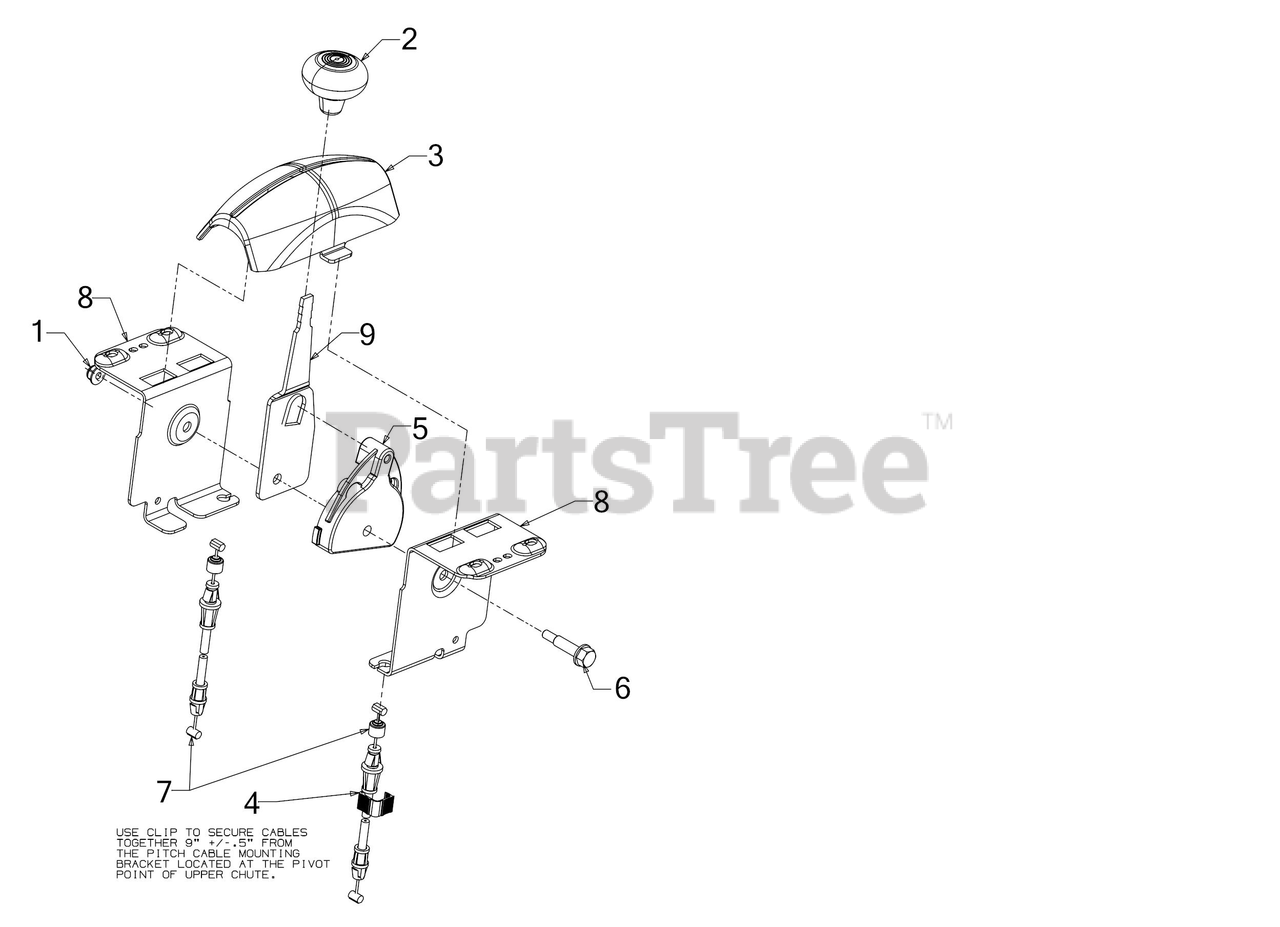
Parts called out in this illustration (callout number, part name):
1	FLANGE LOCK NUT
2	SHIFT KNOB
3	2 WAY CONTROL COVER
4	CABLE CLIP
5	CABLE GUIDE
6	SHOULDER SCREW
7	2-WAY CHUTE CONTROL CABLE
8	2 WAY CONTROL BRACKET
9	2-WAY CONTROL LEVER
